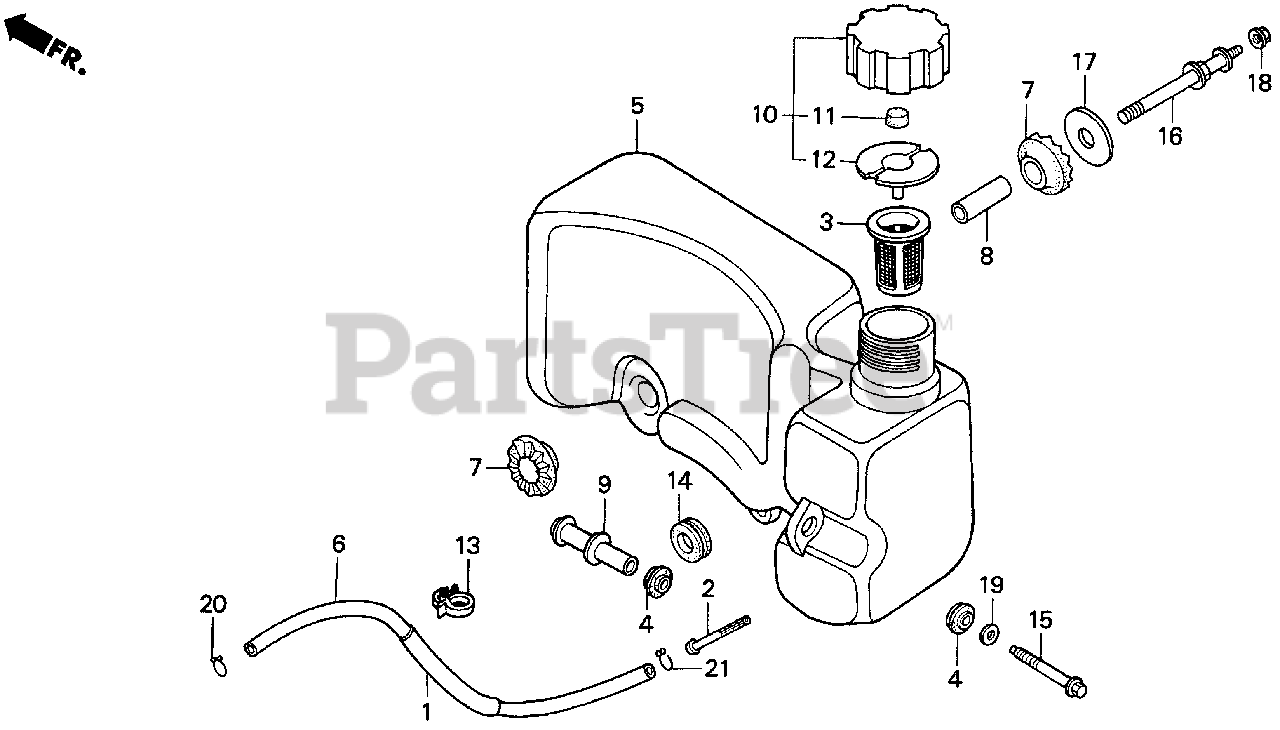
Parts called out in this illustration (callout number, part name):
1	RUBBER, SUPPORTER (107MM)
2	FILTER, FUEL
4	RUBBER, TANK SETTING
5	TANK, FUEL
6	TUBE, FUEL
7	RUBBER B, TANK MOUNTING
8	COLLAR, TANK SETTING
9	COLLAR, TANK
10	CAP ASSY., FUEL TANK
11	SPONGE, FUEL CAP BREATHER
12	GASKET, FUEL CAP
13	CLIP, IGNITION WIRE (8MM)
14	RUBBER, RR. FENDER
15	BOLT, FLANGE (6X50)
16	BOLT, TANK STAY
17	WASHER, TANK MOUNTING
18	NUT, FLANGE (6MM)
19	WASHER, PLAIN (6MM)
20	CLIP, TUBE (B8)
21	CLIP, TUBE (C11)
